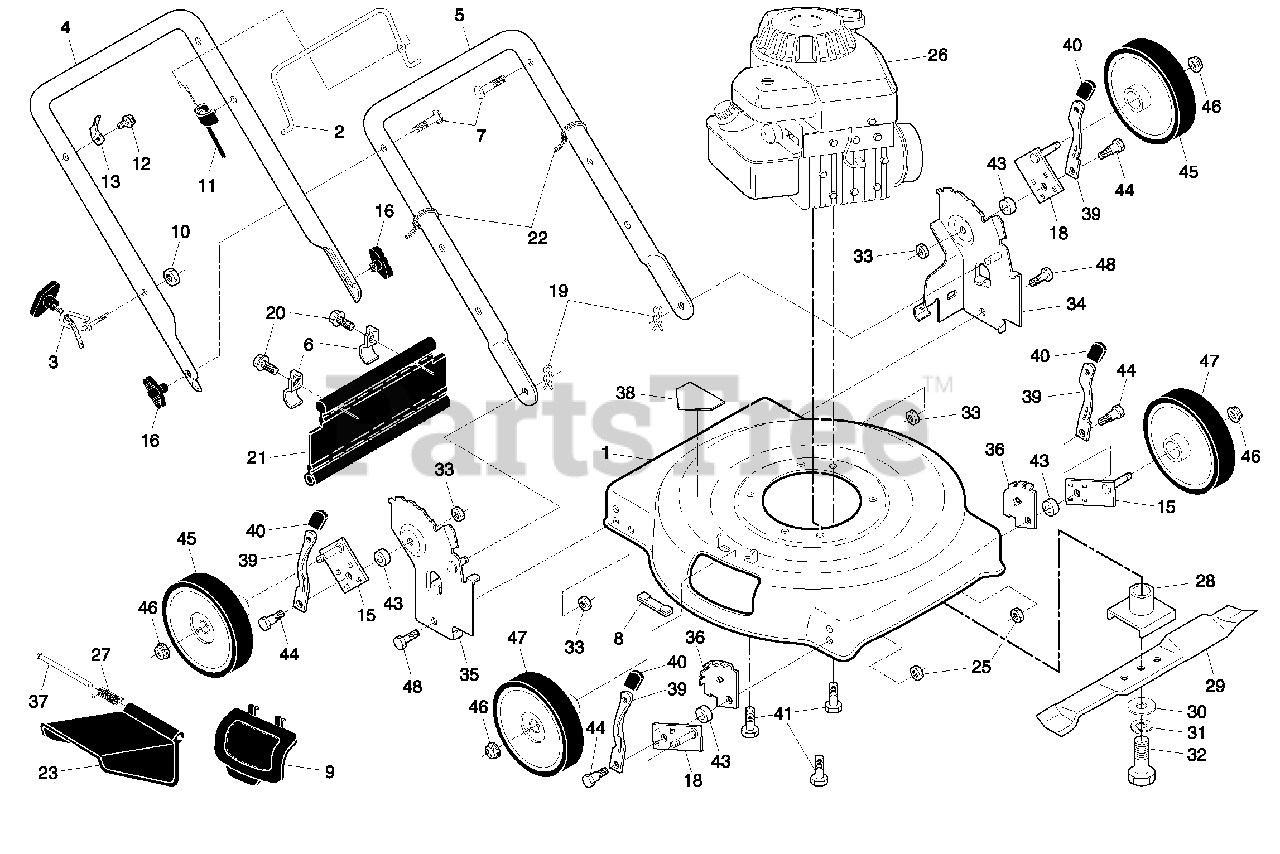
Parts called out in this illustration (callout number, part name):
1	Lawn Mower Housing
2	Control Bar
3	Rope Guide
4	Upper Handle
5	Lower Handle
6	Shoulder Bolt 5/16-18 x .51
7	Handle Bolt 5/16-18
8	Clip, Closeout
9	Mulcher Plate
10	Locknut, Hex 1/4-20
11	Engine Zone Control Cable
12	Hex Washer Head Screw #10-24 x 1/2
13	Up-Stop Bracket
15	Axle Arm Assembly (Front, LH / Rear, RH)
16	Knob, Handle
18	Axle Arm Assembly (Front, RH / Rear, LH)
19	Hairpin Cotter
20	Screw
21	Rear Skirt
22	Wire Tie
23	Discharge Guard
25	Nut, Hex
27	Torsion Spring
28	Blade Adapter
29	22" Blade
30	Hardened Washer
31	Helical Lockwasher 3/8
32	Screw, Hex Head 3/8-24 x 1-3/8 Grade 8
33	Nut, Hex, Flangelock 5/16-18
34	Wheel Bracket Support, LH
35	Wheel Bracket Support, RH
36	Bracket, Wheel Adjuster
37	Hinge Rod
38	Danger Decal
39	Selector Spring
40	Selector Knob
41	Screw, Hex Head, Threaded, Rolled 3/8-16 x 1
43	Spacer
44	Shoulder Bolt 5/16-18 x .33
45	Wheel & Tire Assembly, Rear 8 x 1-3/4
46	Locknut, Hex 3/8-16
47	Wheel & Tire Assembly, Front 7 x 1-3/4
48	Screw, Hex Head, Serrated, Type TT 1/4 x 20
48	Operator's Manual, English
48	Operator's Manual, Spanish
48	Repair Parts Manual
48	Grass Catcher
